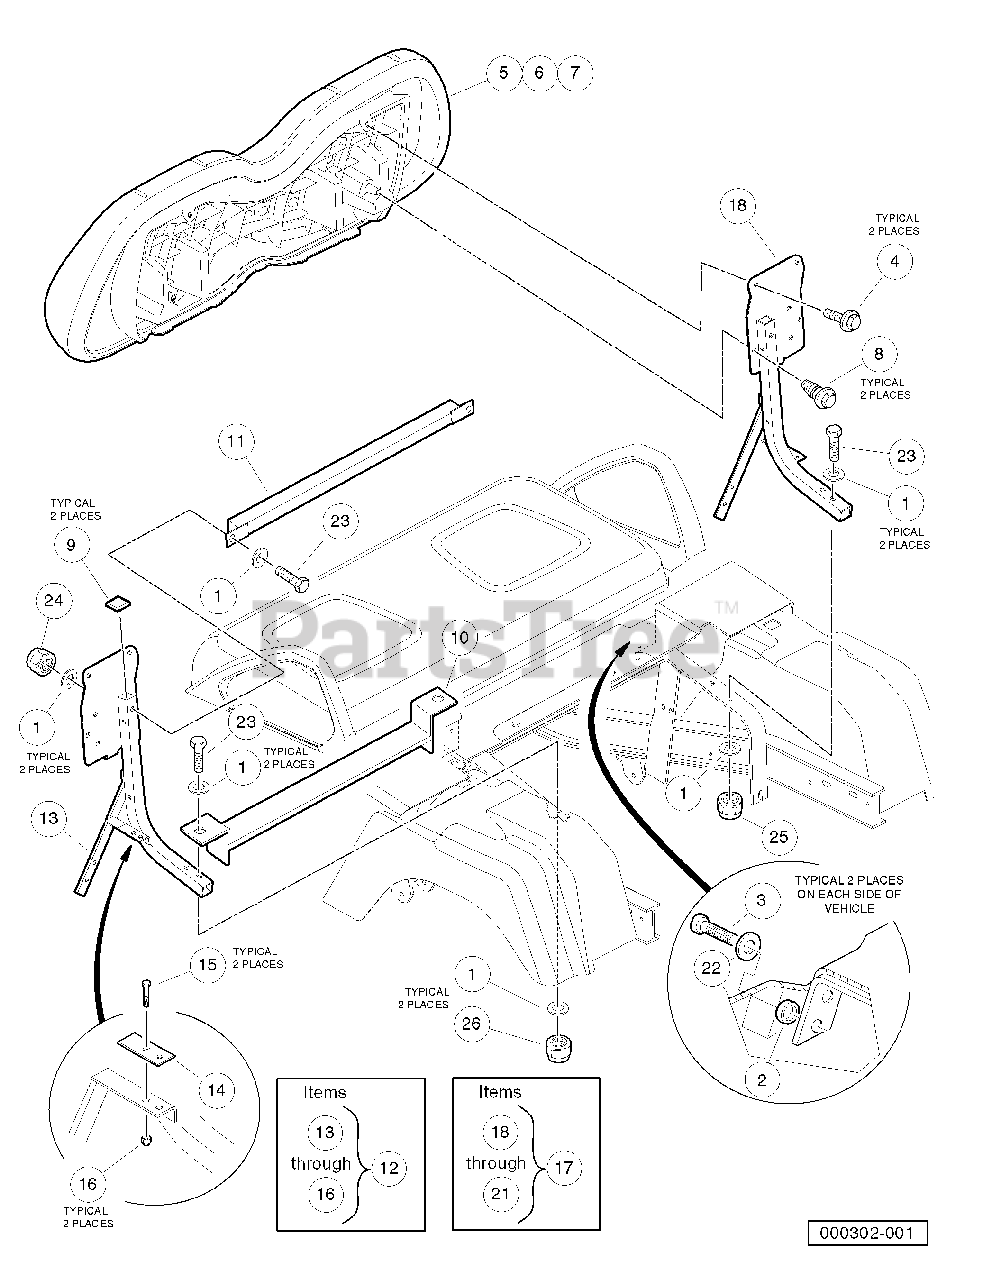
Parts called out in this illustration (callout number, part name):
1	Washer, 1/4 Flat
2	Body Spacer
3	Screw, 5/16-18 X 1.25 Thrd Frm
4	Screw - M6 X 1.0 X 30 Sems
5	Service Backrest Asm, Beige
6	Service Backrest Asm, White
7	Service Backrest Asm, Gray
8	Screw, M6 Hex
9	Plug, Square - 25.4 mm
10	Weldment, Bed Support
11	Seat Support, Cross Brace
12	Seat Support W/striker, Drv
13	Seat Support, Driver-Side
14	Striker Plate
15	Screw, 1/4-20 X 0.75 Hex-Head Cap
16	Locknut, 1/4-20 Nylon Insert
17	Support, Seat, Right
18	Seat Support, Passenger-Side
19	Striker Plate
20	Screw, 1/4-20 X 0.75 Hex-Head Cap
21	Locknut, 1/4-20 Nylon Insert
22	Washer, 5/16 Type A Flat
23	Screw, 1/4-20 X 2.00 Hex-Head Cap
24	Locknut, 5/16-18 Nylon Insert
25	Locknut, 1/4-20 Nylon Insert
26	Screw, 5/16-18 X 1.75 Hex-Head Cap
